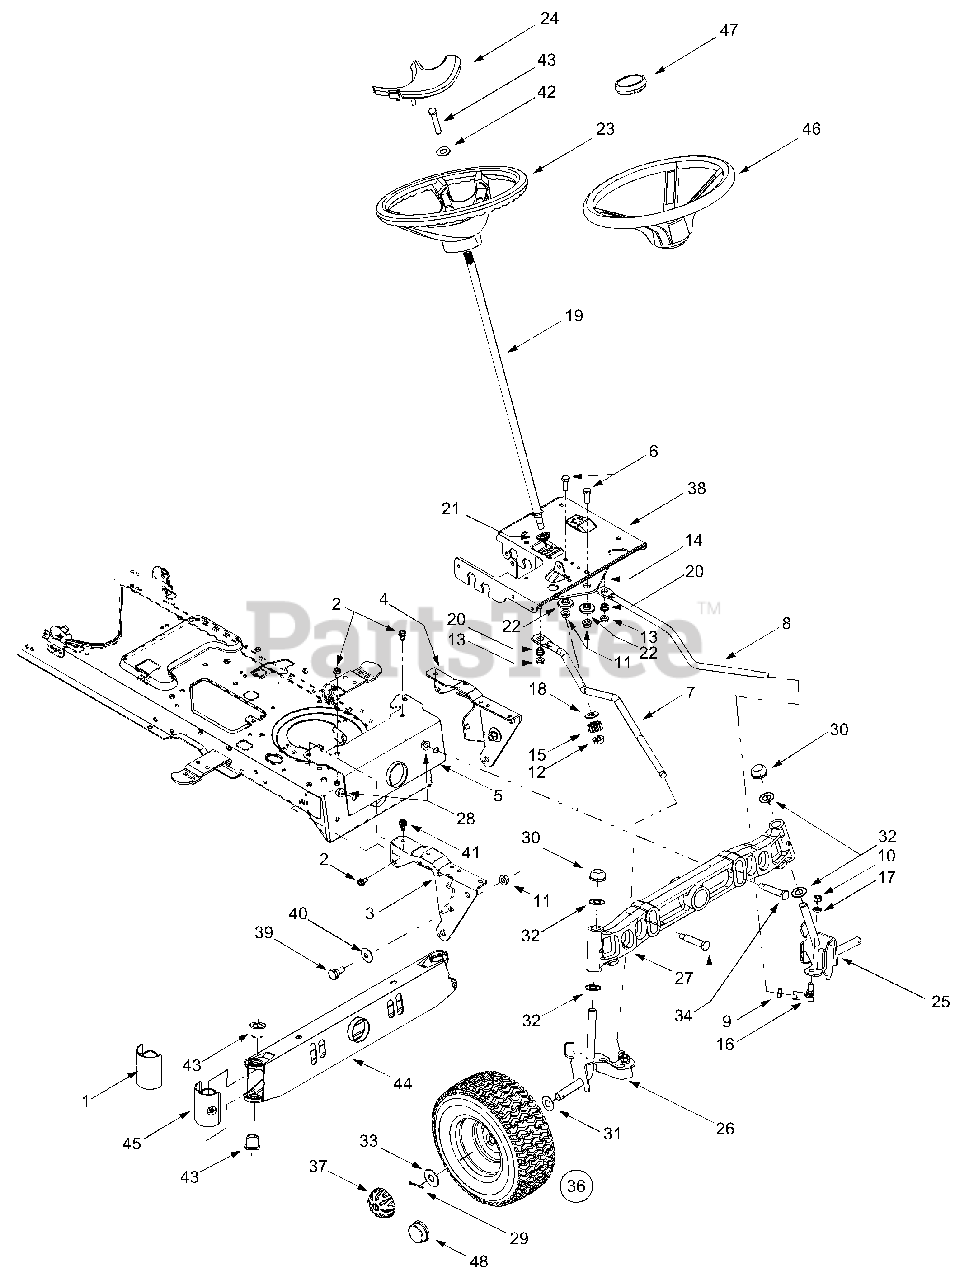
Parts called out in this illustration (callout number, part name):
1	Pivot Bar End Cap w/o Fitting
2	Self-tapping Screw, 16-18 x .625
6	Hex Cap Screw, 3/8-16 x 1 (Grade 5)
7	RH Drag Link
8	LH Drag Link
9	Jam Nut, 7/16-20 (Grade 2)
10	Hex Nut, 3/8-24 (Grade 2)
11	Flange Lock Nut, 3/8-16
12	Flange Lock Nut, 7/16-20
13	Flange Lock Nut, 5/16-18
14	Steering Gear, 11/90 Ratio
15	Steering Pinion Gear
16	Ball Joint, 7/16-20
17	Lock Washer, 3/8
18	Flat Washer, .51 x 1.12 x .06
19	Steering Shaft, .625 OD x 24.4
20	Plastic Bushing, .38 ID
21	Hex Flange Bearing, 5/8
22	Shoulder Spacer, .38 ID
23	Deluxe Steering Wheel
24	Steering Wheel Cap, w/ Icon
25	LH Axle Assembly, .75 Diameter
26	RH Axle Assembly, .75 Diameter
27	Cast Iron Pivot Bar w/ Fittings, .75
28	Flange Lock Nut, 3/8-16
29	Cotter Pin
30	Push Cap, .625
31	Flat Washer, .64 x 1.0 x .12
32	Flat Washer, .78 x 1.59 x .06
33	Flat Washer, .635 x 1.589 x .06
34	Shoulder Screw, .5 x 2.2, 3/8-16
35	Hex Bolt, 5/16-18 X 1
37	Deluxe Hub Cap
39	Shoulder Screw, 3/8-16
40	Bell Washer, .39 x 1.13 x .062
41	Self-tapping Screw, 5/16-18 x .75
42	Bell Washer, .34 x .872
43	Flange Bearing, .760 ID x .937 OD
45	Pivot Bar End Cap w/ Fitting
46	Standard Steering Wheel, 13.25
47	Steering Wheel Cap, Round
48	Standard Hub Cap
